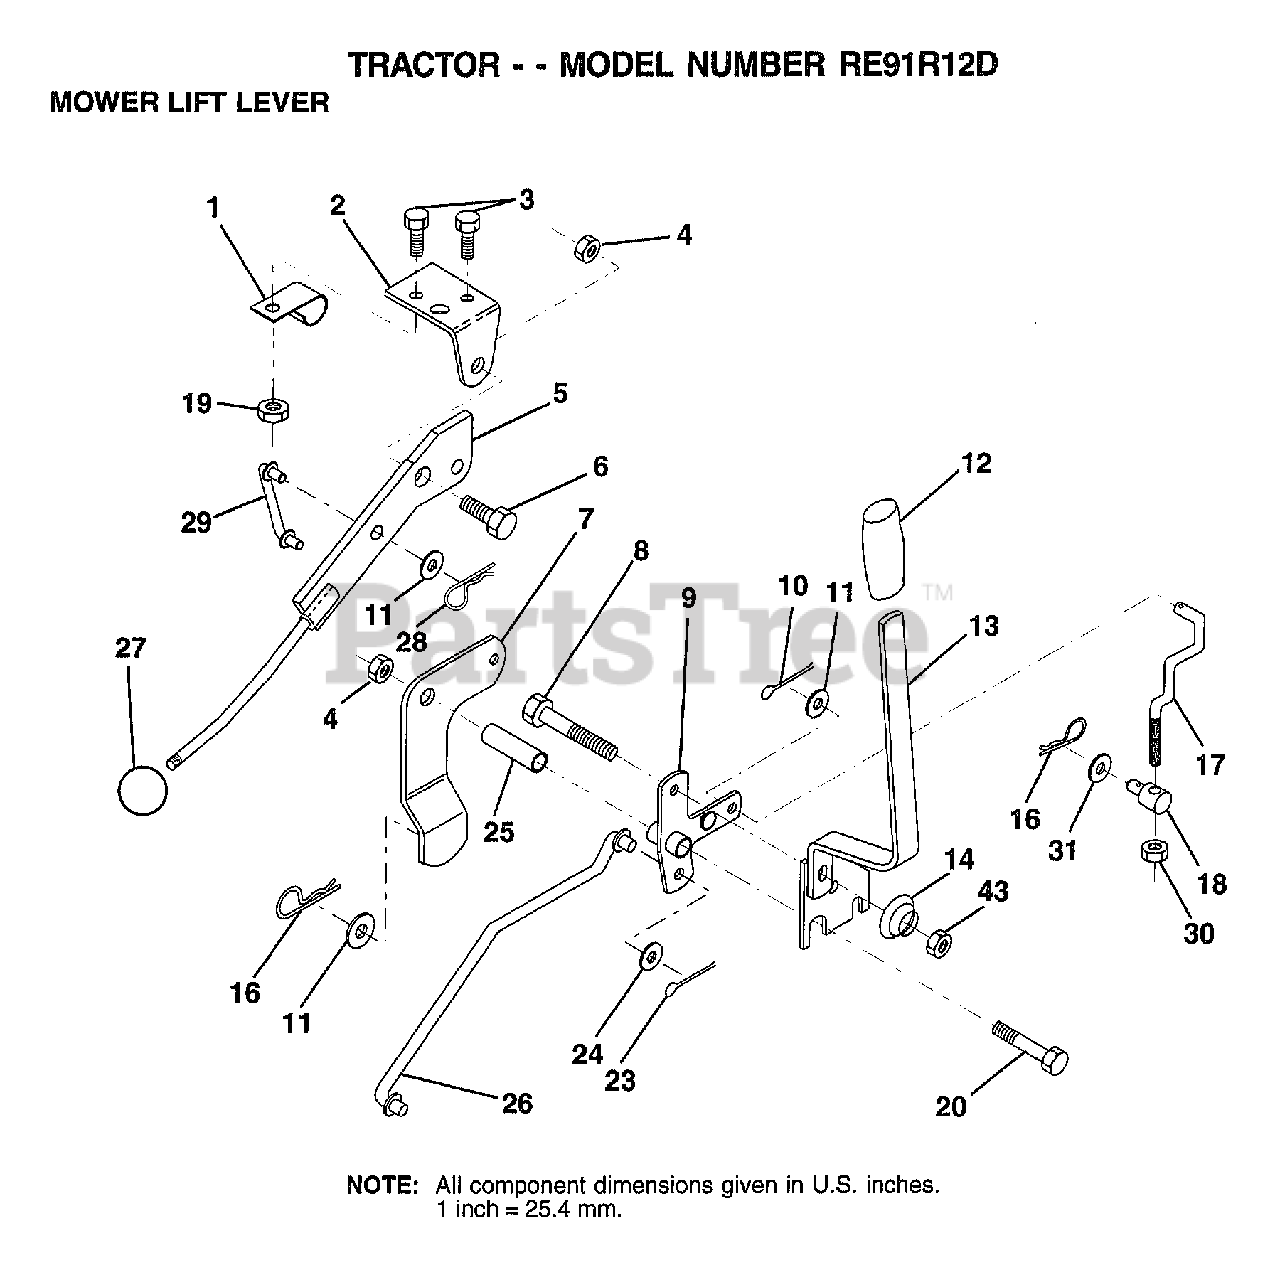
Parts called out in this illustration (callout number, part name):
1	"CLIP,INSULATOR"
2	BRKT CLUTCH
3	BOLT HXHD FIN
5	LEVER.ASM.CLUTCH
6	"BOLT, SHOULDER LT"
7	MWR CLUTCH ARM AS
8	BOLT
9	"BELLCRANK,LIFT"
10	COTTER PIN
11	WASHER
13	HANDLE.ASM.LIFT
14	SPRING COMPRESSIO
15	WASHER T
16	SPRING.RETAINER
17	"LINK,LIFT FRT"
18	TRUNION ADJ
20	BOLT
23	PIN COTTER 1/8
25	TUBE SPACER
26	ROD LIFT MOWER
27	KNOB T(3/8 HOLE)
29	CLUTCH LINK
30	NUT
31	WASHER
